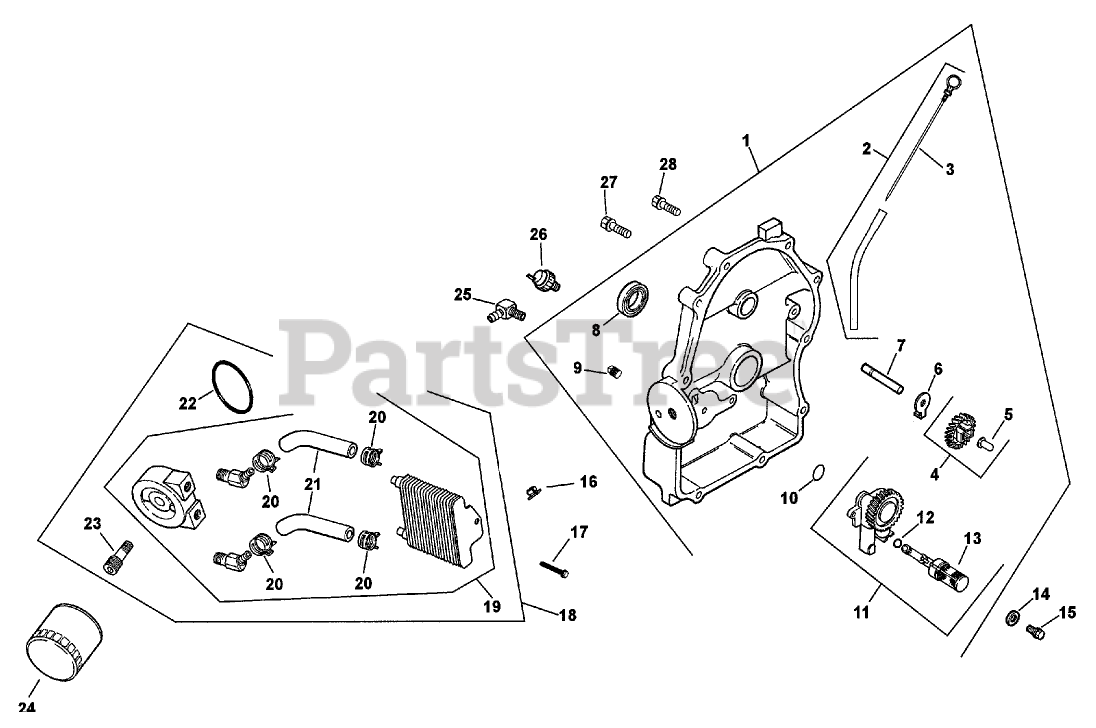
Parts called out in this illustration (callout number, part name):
1	Kit-Plate, Closure (Includes 2-13)
2	Kit-Dipstick & Tube (Includes 3)
3	Dipstick
4	Kit-Gear, Governor (w/pin)(Includes 5)
5	PIN-REGULATING, GOVERNOR
6	Tab-Locking
7	SHAFT-GEAR, GOVERNOR
8	SEAL-OIL (P-T-O END)
9	PLUG-PIPE, COUNTERSUNK (1/8)
10	O-Ring
11	Oil Pump ASM (Includes 12, 13)
12	O-RING
13	TUBE-PICK UP, OIL
14	WASHER-FLAT (6 MM)
15	SCREW-FLANGE, THREAD FORMING (M6X1.0X25)
16	Nut-Plastic
17	SCREW-TAP (M6X1.7X18)
18	Kit-Oil Cooler, Aluminum Base (Includes 19-23)
19	Cooler-Oil (Includes 20, 21)
20	Clamp-Hose
21	Hose, oil
22	O-Ring
23	Nipple-Filter, Oil
24	Filter-Oil
25	Connector-Hose, 90 Deg
26	SWITCH-PRESSURE, OIL
27	Screw-HF (M8x1.25x45)
28	SCREW-FLANGE (M8X1.25X45)
